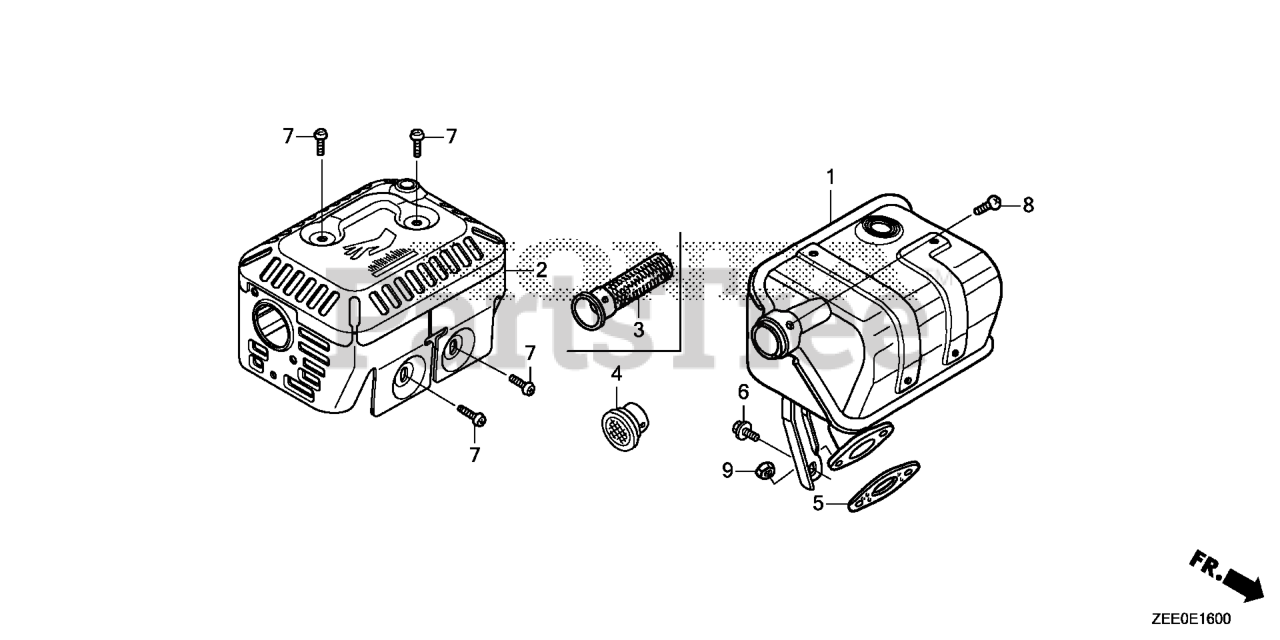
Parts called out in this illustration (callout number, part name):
1	MUFFLER
2	PROTECTOR, MUFFLER
3	ARRESTER, SPARK
5	GASKET, MUFFLER
5	GASKET, MUFFLER (NINGBO SIL GASKET)
6	BOLT, FLANGE (6X13)
7	SCREW, TAPPING (5X8)
8	SCREW, TAPPING (4X6) (TO INSTALL OPTIONAL SPARK ARRESTER)
9	NUT, HEX. (8MM)
